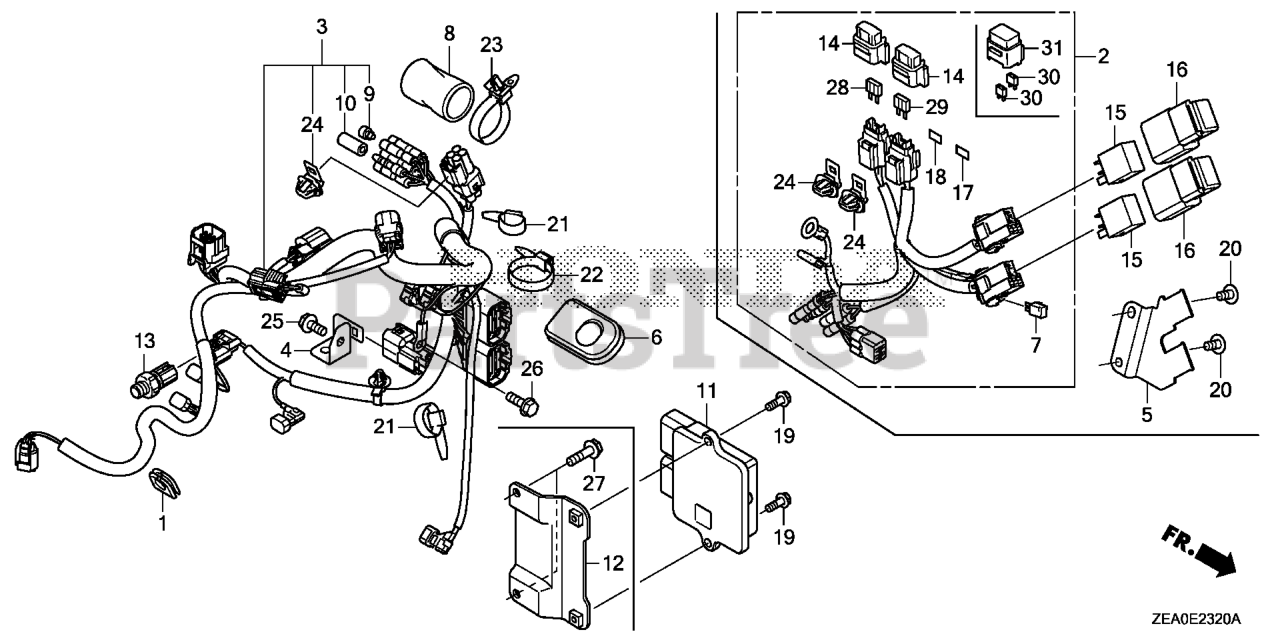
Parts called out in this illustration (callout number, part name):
1	GROMMET, WIRE
3	WIRE HARNESS ASSY., ENGINE
4	BRACKET, HARNESS CLIP
6	GROMMET, WIRE
9	PLUG, CONNECTOR (INNER) (TROLLING CONTROL)
10	PLUG, CONNECTOR (OUTER) (ENGINE NO.)
11	ECU ASSY.
13	SENSOR ASSY., TEMPERATURE
19	BOLT, FLANGE (5X14)
21	BAND, WIRE (95MM)
23	CABLE, STRAP
24	CLIP, CONNECTOR (BLACK)
25	BOLT, FLANGE (6X14)
26	BOLT, FLANGE (6X18)
